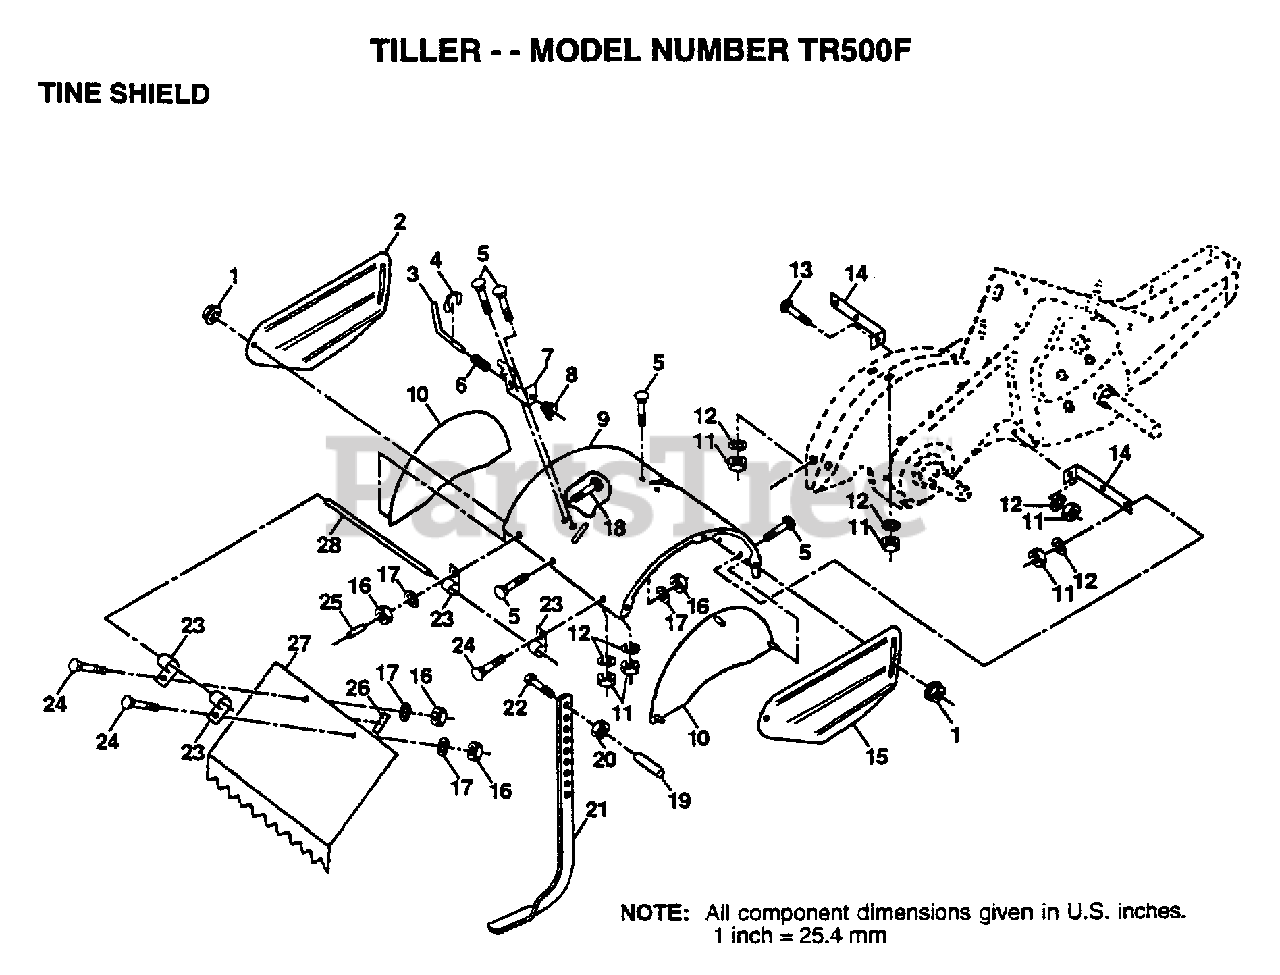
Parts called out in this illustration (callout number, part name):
1	NUT
2	SHIELD.OUT.SD.LH.
3	STAKE PIN TI
4	KLIP RING TI
5	BOLT
6	SPRING TI
7	LATCH BRACKET TI
8	SPRING CRT
9	SHIELD.TINE.PNT.
10	SHIELD.SD.INNER
11	NUT.HEX.5/16-18
12	LOCKWASHER
13	BOLT
14	BRKT SHIELD TINE
15	SHIELD.OUT.SD.RH.
17	LOCKWASHER
18	BOLT
19	GRIP CRT
20	NUT.HEX.3/8-16UNC
21	STAKE DEPTH 16
22	BOLT
23	HINGE CRT
24	BOLT
25	VINYL CAP TI
26	PAD IDLER TI
27	SHIELD.LEVELING
28	PIN HINGE
